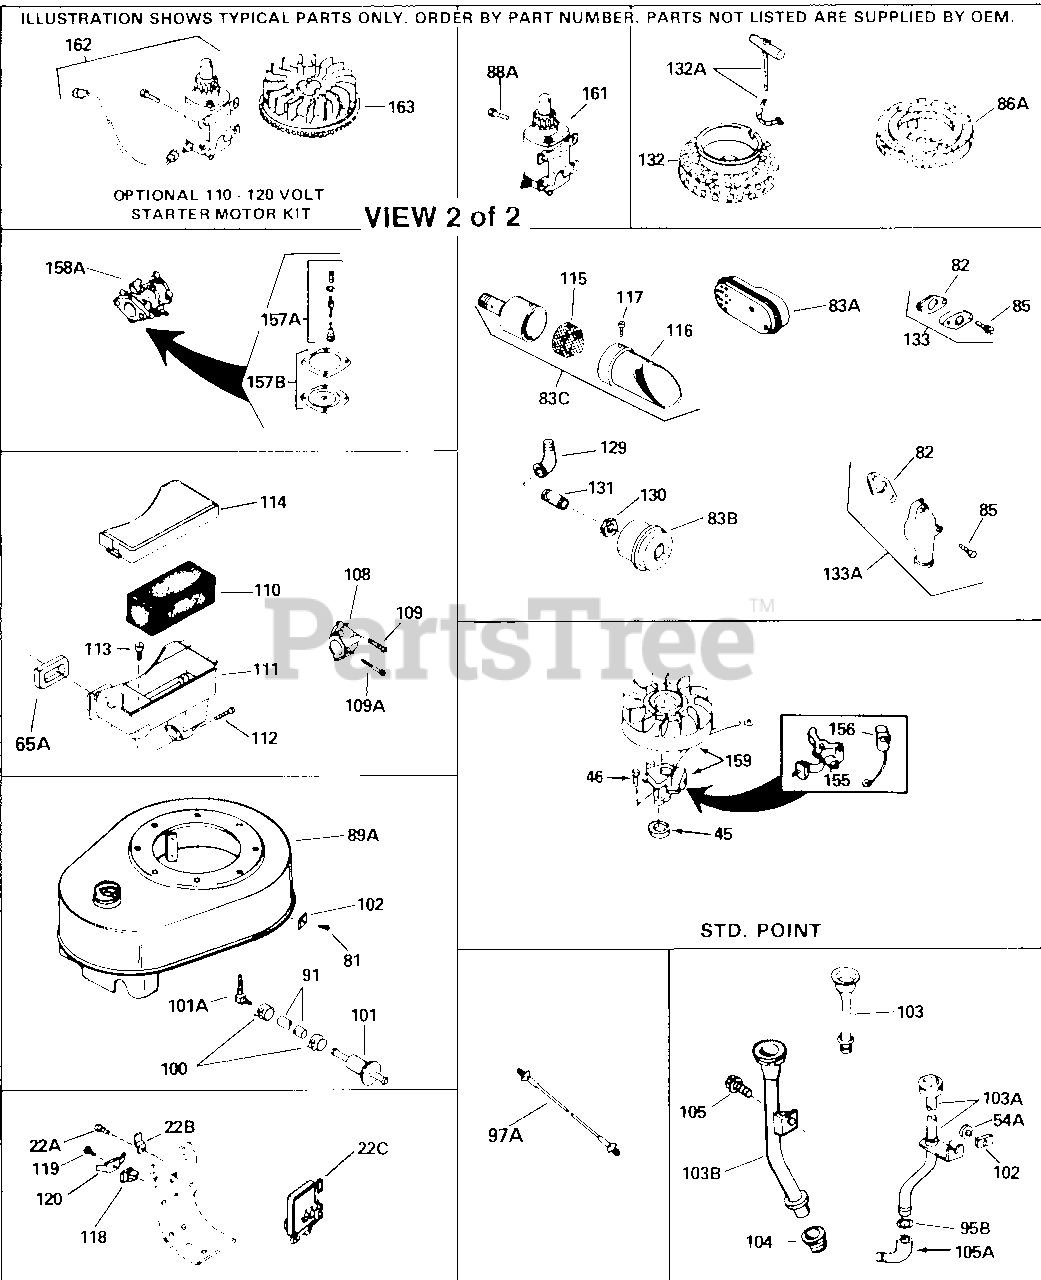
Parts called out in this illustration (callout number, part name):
45	Gasket, Stator
46	Screw, 1/4-20 x 5/8"
54A	Washer, Belleville (Use as required)
65A	* Gasket, Blower housing
81	Screw, T-40, 5/16-24 x 21/32"
82	* Gasket, Exhaust
83C	Muffler (Incl. 115, 116 & 117) (This spark arrestor mufflercan be used on any model)
85	Screw, 5/16-18 x 3/4"
85	Screw, 5/16-18 x 2-3/4" Use as requir ed
85	Screw, 5/16-18 x 2-1/2" Use as requir ed
91	Fuel Line (8.62")
91	Fuel Line (32") (Use as required)
100	Fuel Line Clamp
103	Tube, Oil fill
110	Element, Air cleaner
111	Body, Air cleaner
112	Screw, 10-32 x 1-17/32"
113	Screw, 10-24 x 11/16"
114	Cover, Air cleaner
115	Screen, Muffler (Use as required)
116	Cover & tube, Muffler Use as require d
117	Screw, 8-18 x 3/8" (Use as required)
133	Muffler Adap. Kit (Incl. 82 & 85) As req.
133A	Muffler Adapter Kit (Incl. 82 & 85) A s req.
155	Breaker Points (also available in Pac kaged Part #740037B)
156	Condenser (also available in Packaged Part #740037B)
159	Magneto NOTE: The complete magneto i s not available as an assembly. The magneto number is shown for reference purposes only. Order component part s individually as shown in parts list . (Refer to Division 5, Section B, pa ge 39 for breakdown)
162	Starter Motor Kit (110-120 volt) (Ref er to service number stamped on end c ap of motor, or on decal, for identif ication. For breakdown see Division 5, Section D, Page 16.)
163	Flywheel (Ring gear flywheel required on engines using 110-120 volt starter motor kits listed above) (Use on Std . point ignitions)
163	Flywheel (Ring gear flywheel required on engines using 110-120 volt starter motor kits listed above) (Use on sol id state ignitions)
